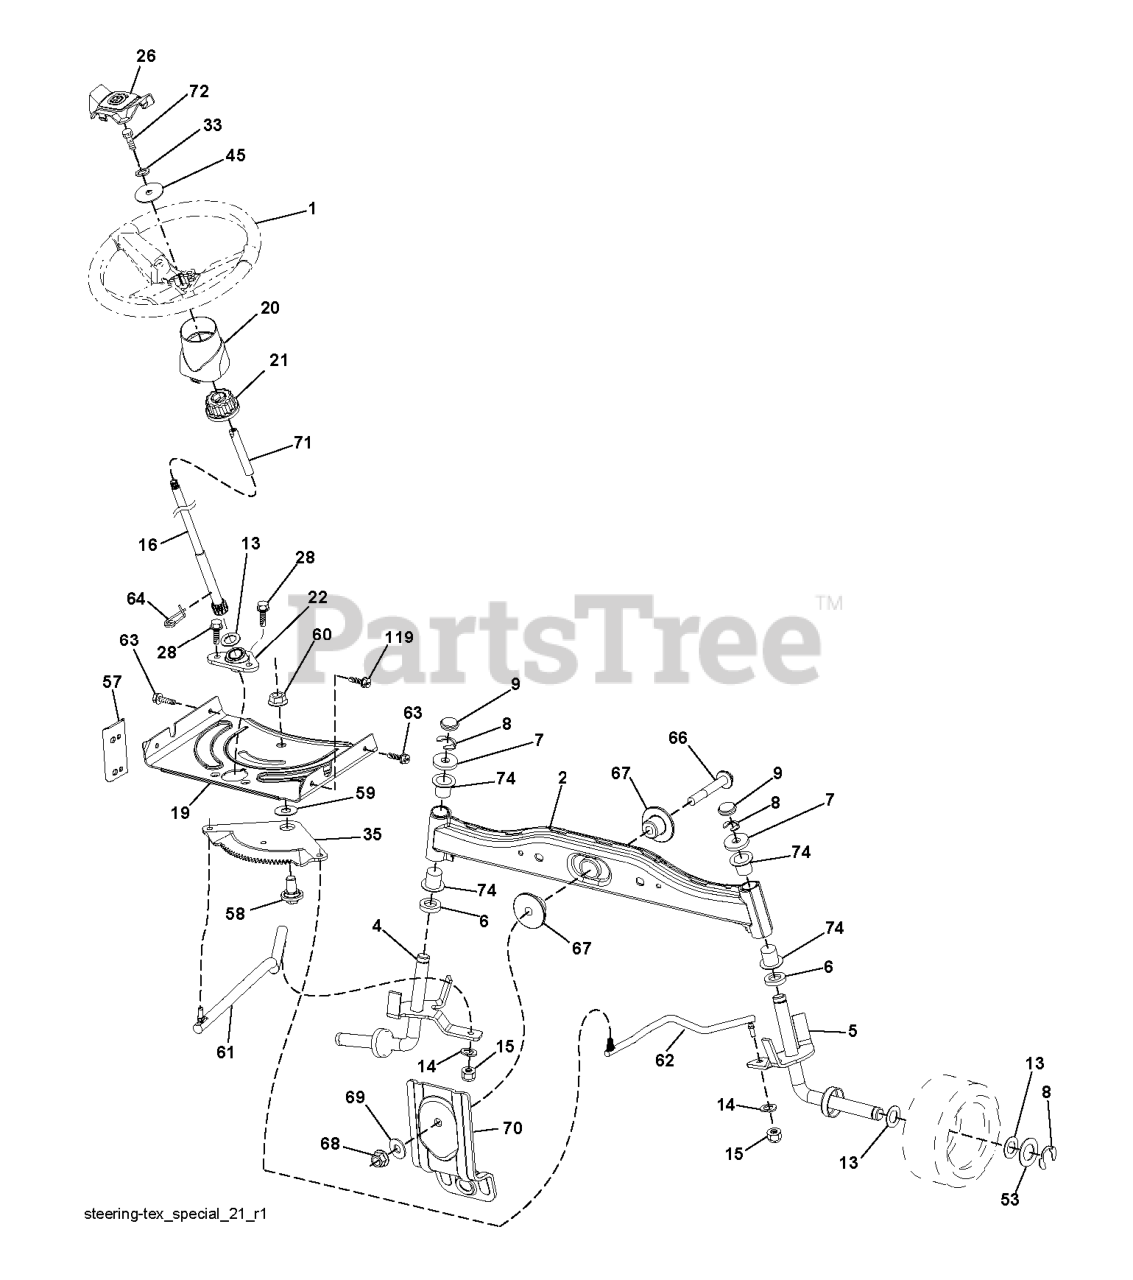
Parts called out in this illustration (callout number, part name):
1	RP WHEEL.STEER.HUSQ.PREM.OVMLD
2	AXLE HALF ASM-WELDED
4	SPINDLE.STEERING.ASM.LH.13".TI
5	SPINDLE.STEERING.ASM.RH.13".TI
6	THRUST WASHER
9	CAP.SPINDLE.BLACK
14	WASHER, LOCK 3/8
15	NUT CROWNLOCK 3/8-24
16	SHAFT STEERING
19	PLATE.STEER.DDL.NLT/NG
20	BOOT, STEERING
21	ADAPTER, WHEEL STNG..
22	BUSHING.ASM.STEERING.A
26	RP INSERT.CAP.WHL.STRG.HUSQ.
28	SCREW, 3/8-16X3/4
33	WASHER.LOCK.HVY.HLCL.SPR.5/16
35	GEAR.SECTOR.PLATE.DDL.
45	WASHER.11/32
53	WASHER.HARDENED
57	BRACKET.UPSTOP.TEX
58	BOLT.SHOULDER.SECTOR.P
59	WASHER.THURST.SECTOR.S
60	NUT FLANGE LOCK 5/8-11
61	DRAGLINK.LH.BALLSTUD.D
62	DRAGLINK.RH.BALLSTUD.D
63	SCREW
64	RETAINER.CLIP.SPRING.S
66	BOLT HEX FGHD 7/16-14 X 3 SERR
67	BUSHING.PM.FRONT AXLE
68	NUT.LOCK.FLANGE.7/16
69	WASHER.1.5X.505X.118
70	BRACKET.SUSP.MWR.FRT.30"SRD
71	SHAFT EXTENSION STEERING
72	BOLT YT
74	BRNG T
119	SHOULDER BOLT 5/16-18TT
